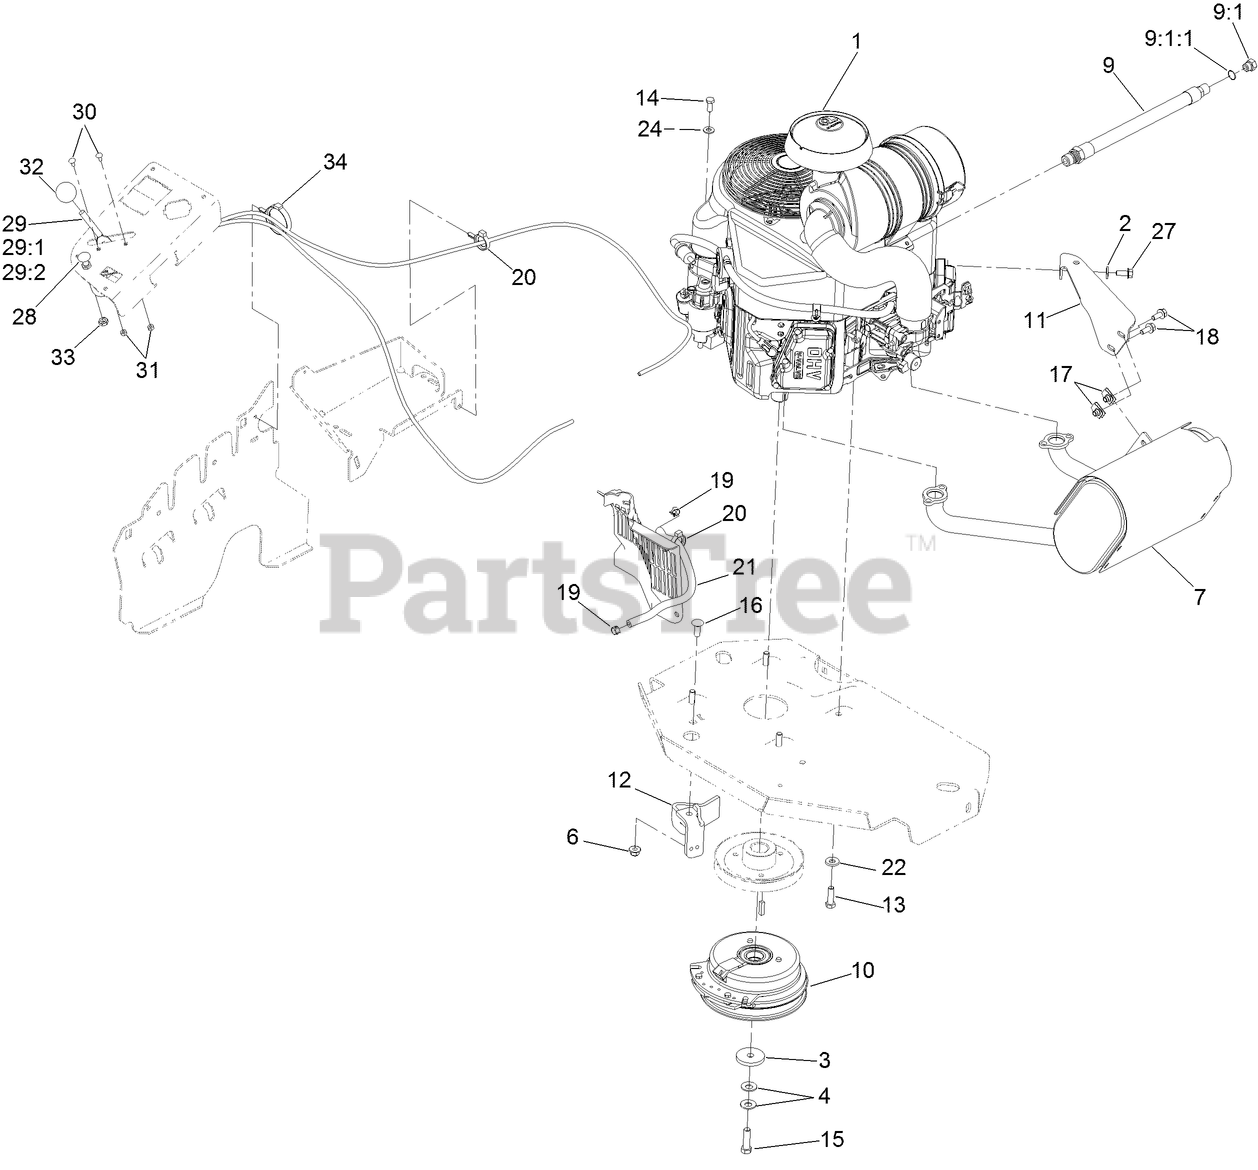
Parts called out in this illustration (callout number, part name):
2	WASHER-SPRING
3	WASHER-CLUTCH
4	WASHER-SPRING
6	NUT-HF, NI
7	MUFFLER
9	ENGINE OIL DRAIN HOSE ASM
9:1	PLUG-HH
9:1:1	O-RING
10	CLUTCH KIT
11	BRACKET-MUFFLER
12	CLUTCH-ANCHOR
13	SCREW-HH
14	SCREW-HH
15	SCREW-HH, W/LOCTITE
16	SCREW-CARR
17	NUT-U
18	SCREW-HH
19	CLAMP-HOSE
20	CLAMP-HOSE
21	HOSE-FUEL
22	WASHER-BELLEVILLE
24	WASHER-PLAIN
27	SCREW-HHF
28	CONTROL-CHOKE
29	THROTTLE CONTROL ASM
29:1	LEVER-THROTTLE
30	BOLT-CARR
31	NUT-LOCK, NI
32	KNOB-BALL
33	NUT-HJ
34	CLAMP-HARNESS
